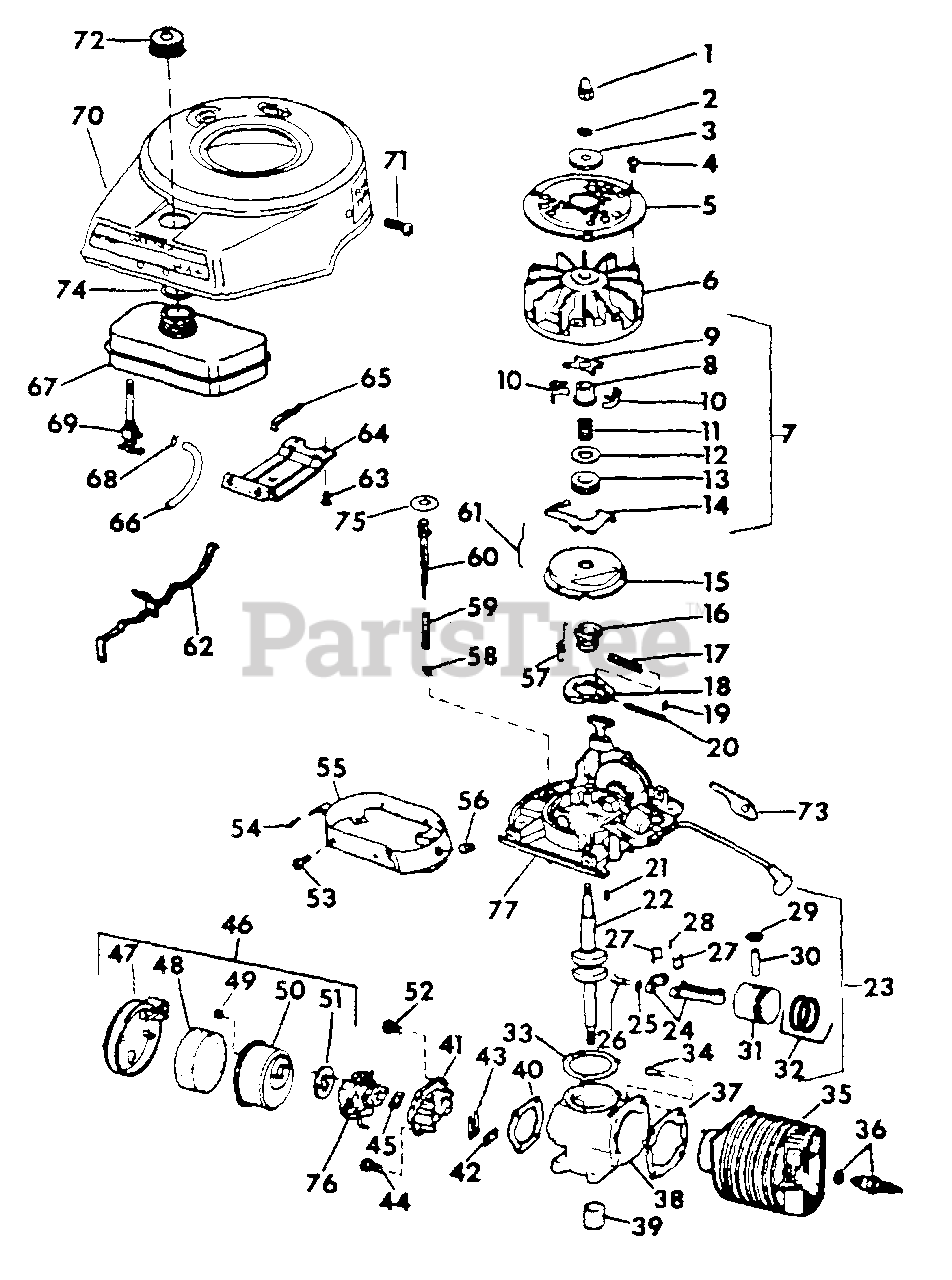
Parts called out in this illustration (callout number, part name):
1	NUT, 7/16-20 HIGH CROWN
2	WASHER, 7/16 ZND INT TOOTH LOCK
4	SCREW, THD CUTTING
5	SCREEN, FLYWHEEL
7	GOVERNOR ASSY
8	COLLAR, GOVERNOR
9	YOKE, GOVERNOR
10	WEIGHT, GOVERNOR
11	SPRING, GOVERNOR
12	WASHER, THRUST
13	COLLAR, THRUST
14	LEVER, GOVERNOR
16	CAM, SPARK ADVANCE
17	SPRING, SPARK ADVANCE
18	FLYWHEEL, SPARK ADVANCE
19	RETAINER, SPRING
20	PIN SPARK ADVANCE
21	KEY, CRANKSHAFT
23	PISTON & CONNECTING ROD ASSY
24	ROD ASSY, CONNECTING
25	LOCKPLATE, SCREW
26	SCREW, CONNECTING ROD
27	LINER, CONNECTING ROD
28	BEARING SET, NEEDLE - PACKED
29	RING, RETAINING
32	RING SET, PISTON (2 RINGS)
33	GASKET, CRANKCASE TO ARM PLATE .010
34	SCREW, CYL TO CRANKCASE
35	CYLINDER & SLEEVE
36	SPARK PLUG & GASKET
37	GASKET, CYL TO CRANKCASE
38	CRANKCASE & SEAL ASSY
40	GASKET, REED PLATE
41	REED PLATE ASSY
42	PLATE, BACKUP
44	SCREW, HH REED PLATE TO CRANKCASE
45	GASKET, CARBURETOR
46	FILTER ASSY AIR
47	CAP - PAINTED WHITE
48	ELEMENT, AIR CHAMBER
50	CHAMBER, AIR - PAINTED WHITE
52	SCREW, HH REED PLATE TO CRANKCASE
53	SCREW, BAFFLE
54	NUT, COVER MTG
56	GROMMET, COVER MTG
57	SPRING, VARIABLE SPEED
58	BLADE, SWITCH
59	SPRING, SHUTOFF SWITCH
60	BAR, SHUT-OFF & PRIMER
61	ROD, GOVERNOR
62	CONTROL & GUIDE, VARIABLE SPEED
64	BRACKET, FUEL TANK
65	SPRING, FUEL TANK
67	FUEL TANK ASSY
68	CLAMP, FUEL TANK HOSE
69	VALVE & SCREEN, SHUT-OFF
70	COVER, ENGINE
71	SCREW, COVER MTG
72	CAP, GAS TANK
74	GASKET, TANK TO SHROUD
76	CARBURETOR ASSY
77	MAGNETO ASSY
